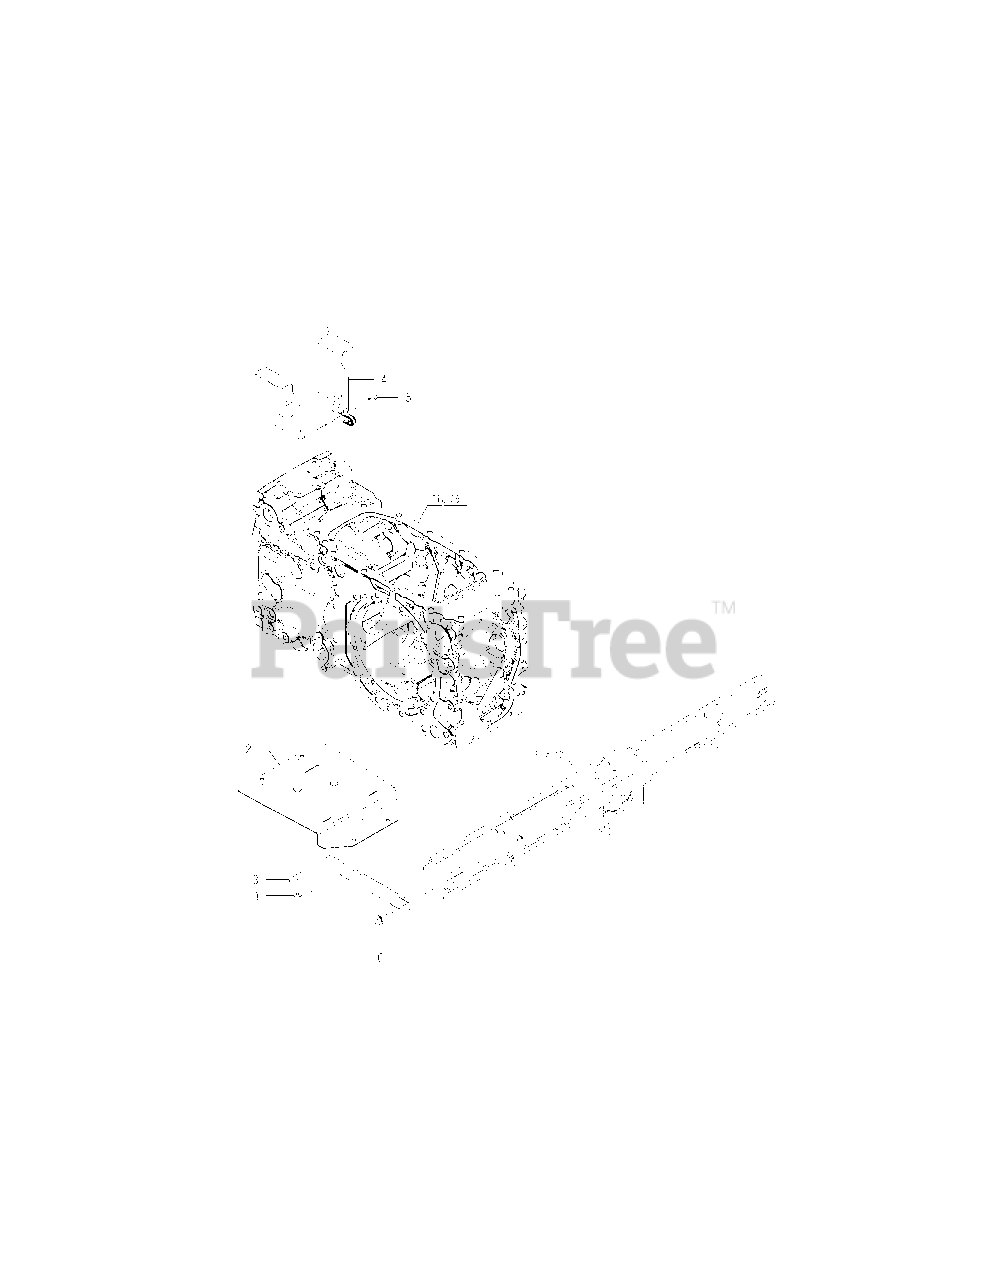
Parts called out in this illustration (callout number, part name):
1	NUT W/WASHER 8
2	COVER, LAMP ASSY
3	BRACKET ASSY, REAR
4	BRACKET ASSY, F UNIT
5	BOLT M 8X 16 PLATED
6	BOLT M 8X 20 PLATED
